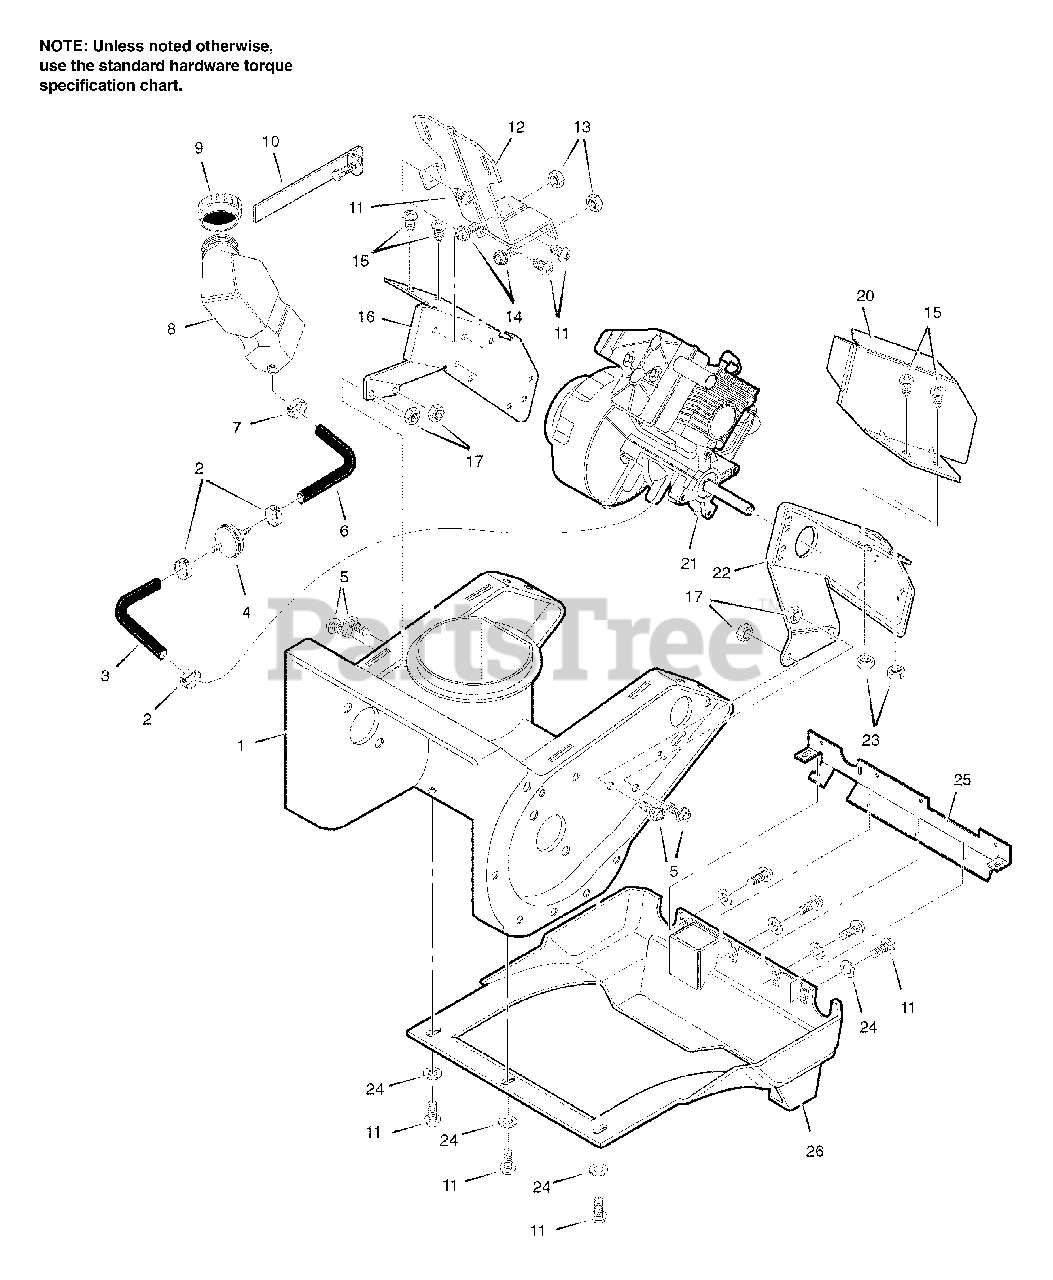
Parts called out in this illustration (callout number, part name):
1	AUGER HOUSING 21"
2	CLAMP, TUBING
3	TUBING, FUEL
4	FILTER, FUEL
5	SCREW .31-18 x .50
6	TUBING, FUEL
7	CLAMP, TUBING
10	CLAMP, WORM DR
11	SCREW 10-24 x .62
12	BRACKET, FUEL TANK
13	NUT, LOCK 10-24
14	SCREW 10-24 x .50
15	SCREW .25-20 x .62
16	PLATE, REAR MT RH
17	NUT, LOCK .31-18
20	HEAT SHIELD
21	ENGINE
22	PLATE, REAR MT LH
23	NUT, LOCK .25-20
24	WASHER, FLAT
25	BRACKET, COVER
26	BOTTOM COVER
